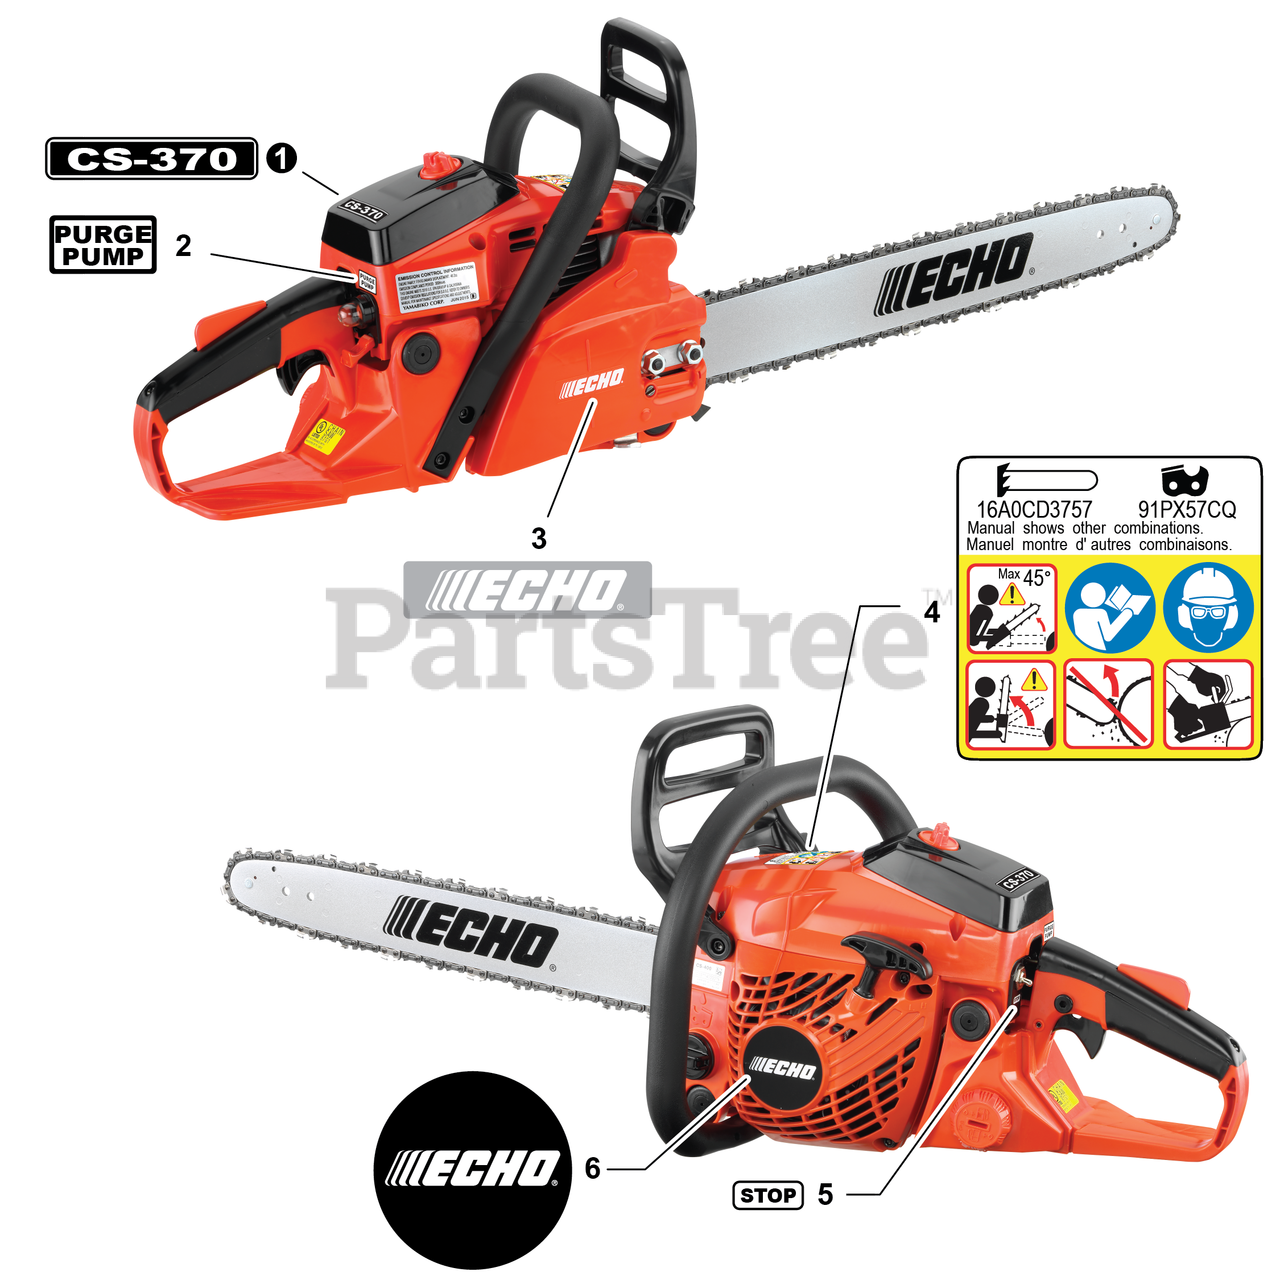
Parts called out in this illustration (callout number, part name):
1	LABEL - MODEL CS-370
2	LABEL, PURGE PUMP
3	LABEL, ECHO
4	LABEL, CAUTION
5	LABEL, STOP
6	LABEL, ECHO
